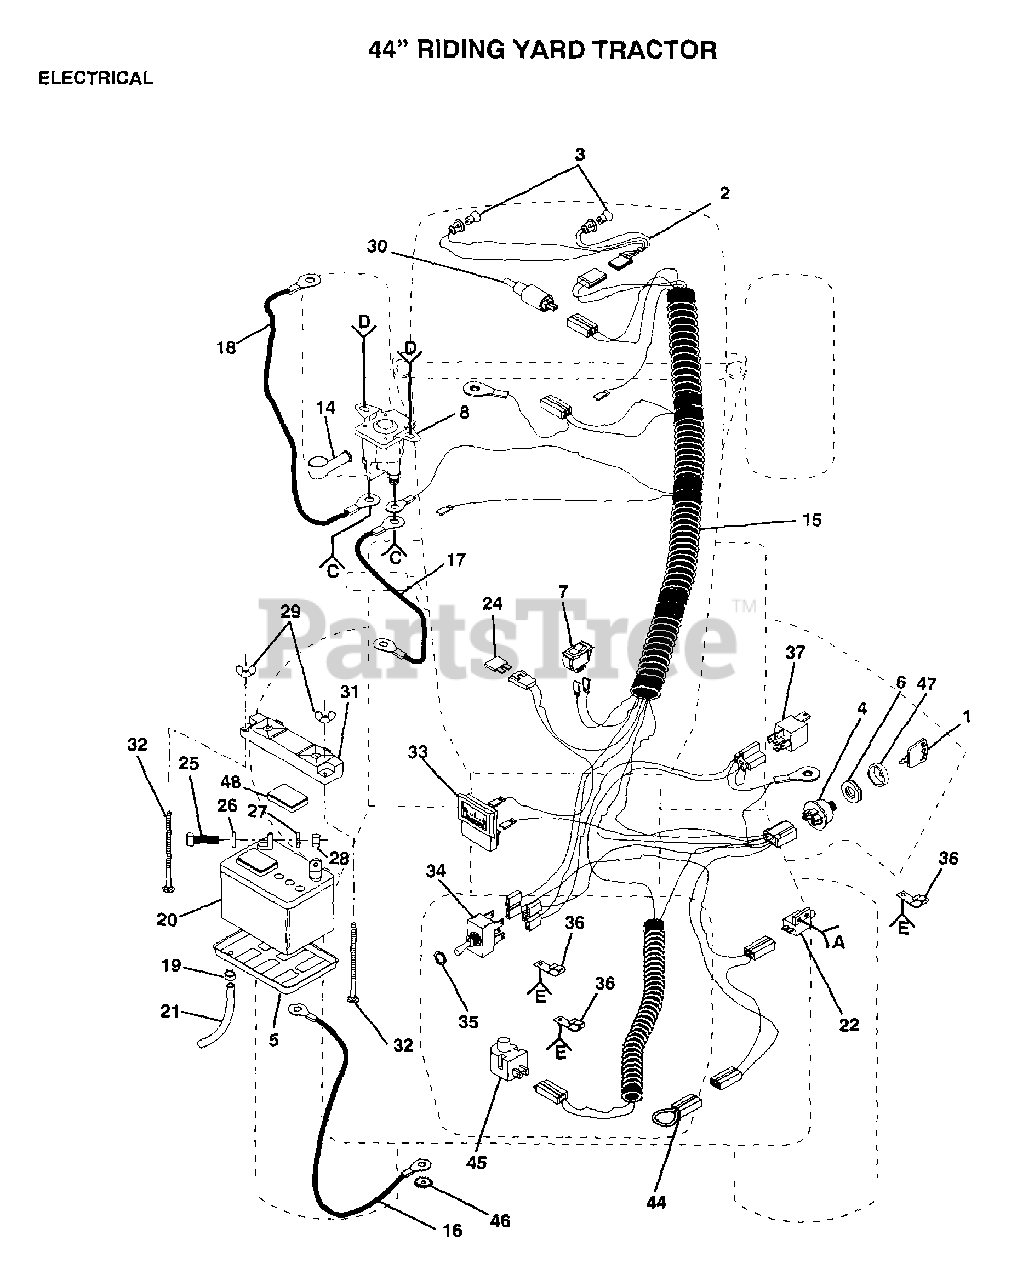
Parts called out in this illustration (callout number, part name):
1	KEY
2	HARNESS T
5	"TRAY T, BATTERY"
7	SWITCH LT
16	"CABLE T, BATTERY"
19	HOSE CLAMP T
22	SWITCH-INTER. GT
24	FUSE HYT
25	BOLT LT
26	WASHER
27	LOCKWASHER
32	BOLT
33	AMMETER
35	HEX NUT T
36	CLIPT
37	RELAY ASSY T
45	SWITCH SEAT
46	LOCKWASHER
48	"CAP,BATTERY "
